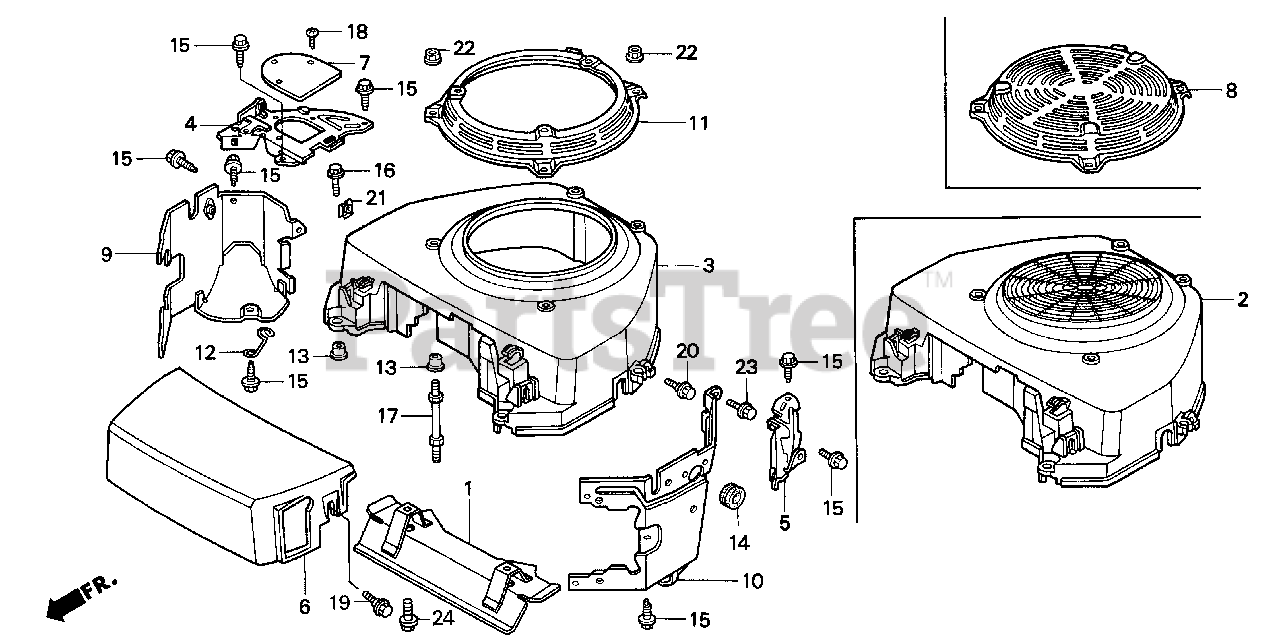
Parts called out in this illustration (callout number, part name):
2	COVER, FAN *R8* (BRIGHT RED)
2	COVER, FAN *NH1* (BLACK)
4	PLATE, R. SIDE
5	PLATE, L. SIDE
6	HOOD, FAN COVER
9	SHROUD, R.
10	SHROUD, L.
12	CLAMP, IGNITION TUBE
13	COLLAR B, TAILLIGHT
14	RUBBER, BRACKET MOUNTING
15	BOLT, FLANGE (6X12) (CT200)
16	BOLT, FLANGE (6X23)
17	BOLT, STUD (6X75)
19	BOLT, FLANGE (6X20)
20	BOLT, FLANGE (6MM) (BLACK)
21	NUT, SPRING (6MM)
22	NUT, FLANGE (6MM)
23	BOLT, FLANGE (6X8)
